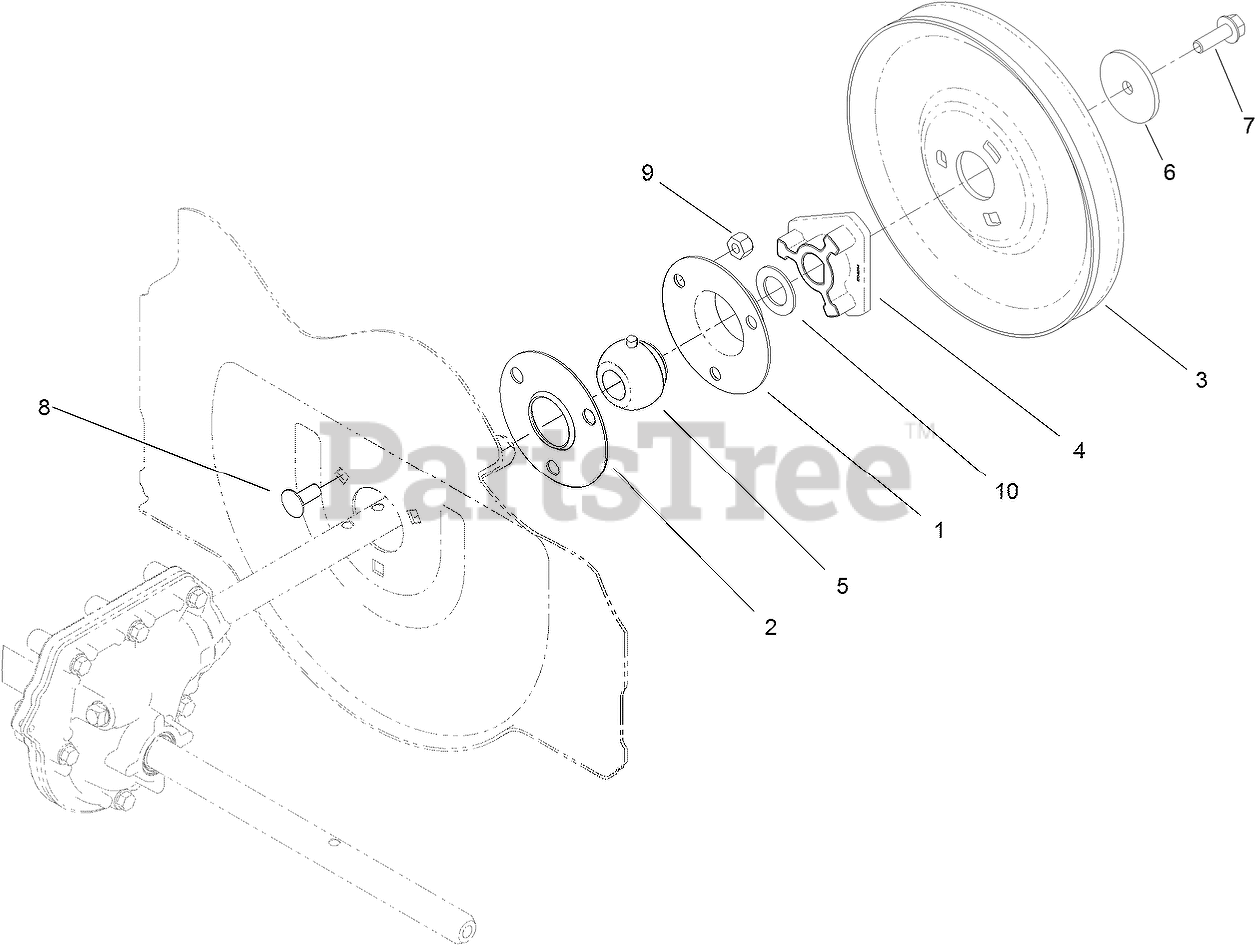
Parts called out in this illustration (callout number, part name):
1	FLANGE-CUP, BEARING
2	FLANGE-CUP, BEARING
3	PULLEY-IMPELLER
4	HUB-IMPELLER, PULLEY
5	BEARING
6	WASHER-PLAIN
7	SCREW-HHF
8	SCREW-CARR
9	NUT-LOCK, NI
10	WASHER-THRUST
